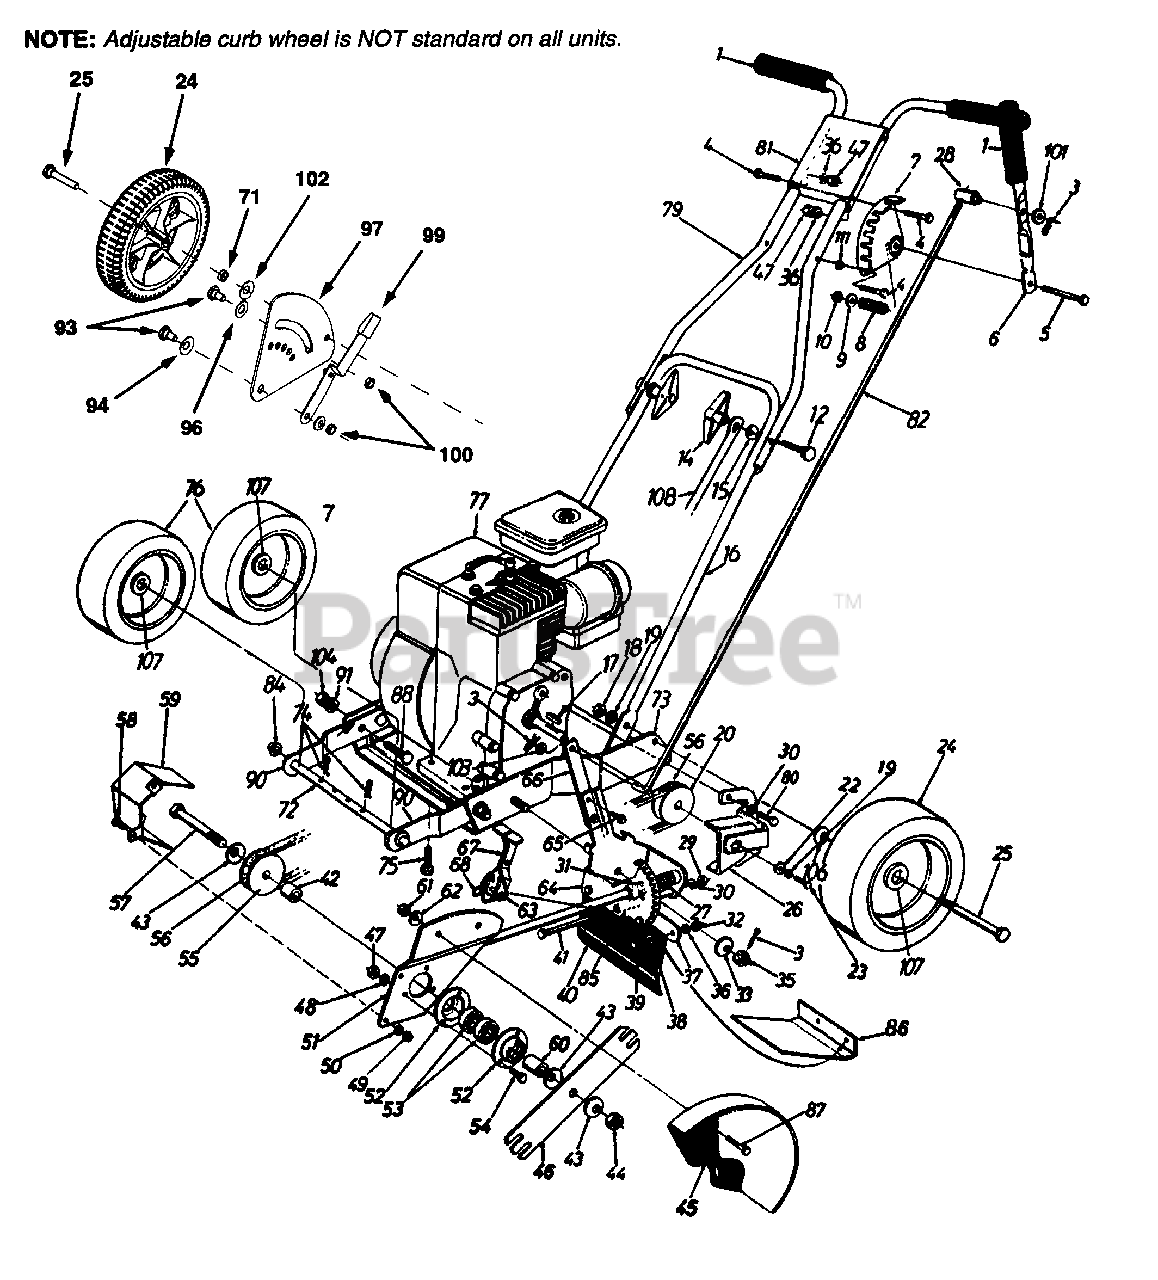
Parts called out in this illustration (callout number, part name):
3	Cotter Pin 5/16" Dia.
4	Hex Bolt 1/4-20 x 1.25" Lg.
5	Hex Bolt 5/16-18 x 2" Lg.
8	Compression Spring 1.38" Lg.
9	Flat Wash. .344" I.D.
10	Hex L-Nut 5/16-18 Thd.
12	Curv. Hd. Bolt 5/16-18 x 2" Lg.
14	Wing Nut Ass'y.
15	Saddle Wash. .32" I.D. x.937"
18	Hex Nut 3/8-16 Thd.
19	L-Wash. 3/8" I.D.
20	Engine Pulley
22	Flat Wash. .385" I.D.
23	Hex Bolt 3/8-24 x 1" Lg.
24	Wheel, Slot Bar Gray
25	Shoulder Bolt .498" Dia.
28	Ferrule
29	Hex Nut 5/16-18 Thd.
30	L-Wash. 5/16" I.D.
31	Spring Pin Spir. 1/4" Dia.
32	Hex Nut 1/4-20 Thd.
33	Bell Wash. .535" I.D.
35	Hex Slotted Nut 1/2-20 Thd.
36	L-Wash. 1/4" I.D.
39	Hex Bolt 1/4-20 x .62" Lg.
41	Hex Bolt 5/16-18 x 4.5" Lg.
42	Spacer 1.030" Lg.
43	Bell Washer.63" I.D.
44	Hex Jam L-Nut 5/8-18 Thd.
47	Hex Nut 1/4-20 Thd.
48	L-Wash. 1/4" I.D.
49	Hex Nut 1/4-20 Thd.
50	L-Wash. 1/4" I.D.
53	Ball Bearing .62" I.D.
54	Hex Bolt 1/4-20 x .62" Lg.
55	3/8" "V"-Pulley
56	"V"-Belt
57	Hex Bolt 5/8-18 x 4.5" Lg.
58	Hex Bolt 1/4-20 x .625" Lg.
60	Sleeve .90" Lg.
61	Hex Nut 5/16-18 Thd.
62	Bell Wash. .345" I.D.
63	Spring Pin Spir. 1/4" Dia.
68	Torsion Spring
71	Spacer
72	Axle 8.20" Lg.(Front)
75	Hex TT-Tap Scr. 3/8-16 x 1" Lg.
76	Wheel, Slot Bar Gray
77	Engine
84	Push Cap 1/2" Dia.
85	Spacer 3.765" Lg.
88	Ribbed Neck Bolt 3/8-24 x .8" Lg.
93	Shld. Bolt .5" Dia.
94	Bell Wash .515" I.D.
96	Flat Wash .51" I.D. x 1.0" O.D.
100	Hex Jam Nut 3/8-16 Thd.
101	Flat Wash.344" I.D. x .62" O.D.
102	Wave Wash. .51" I.D.
103	Flat Washer.406" I.D. x.81" O.D.
104	Hex Nut 3/8-24 Thd.
106	Bell Washer.38" I.D. x.88" O.D.
